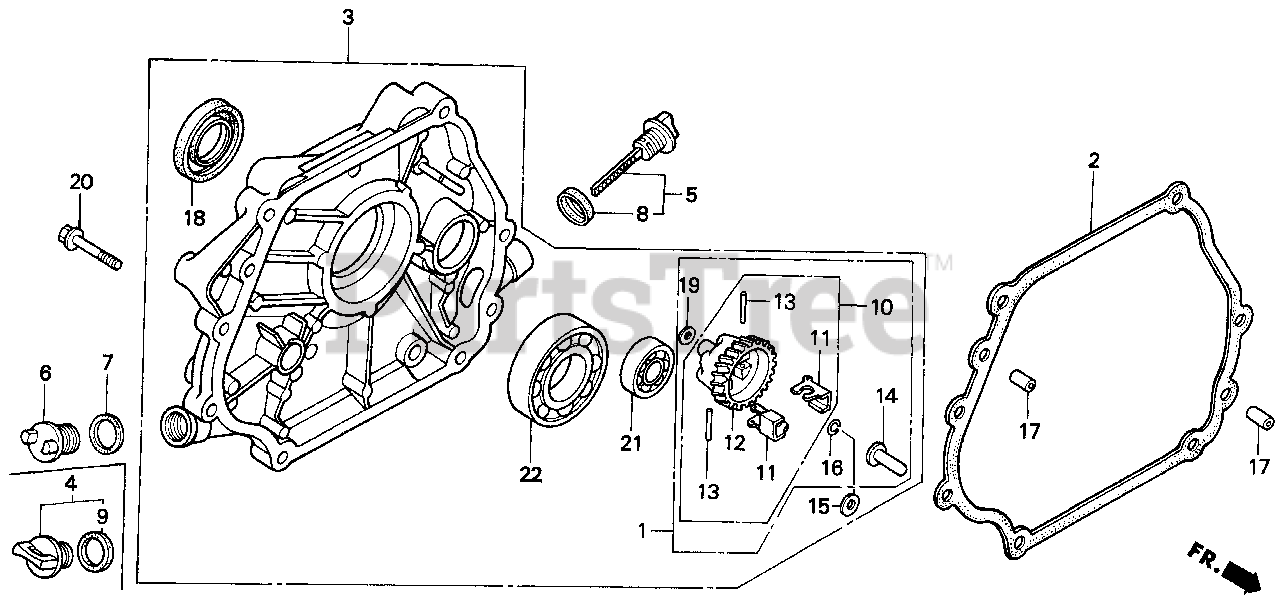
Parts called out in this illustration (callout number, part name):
1	GOVERNOR KIT (BALANCER)
2	GASKET, CASE COVER
3	COVER ASSY., CRANKCASE (Q-TYPE)(BALANCER)
5	CAP ASSY., OIL FILLER
6	CAP, OIL FILLER
7	GASKET, OIL FILLER CAP
8	GASKET, OIL FILLER CAP
10	GOVERNOR ASSY. (BALANCER)
11	WEIGHT, GOVERNOR
12	HOLDER, GOVERNOR WEIGHT
13	PIN, GOVERNOR WEIGHT
14	SLIDER, GOVERNOR
15	WASHER (6X16)
16	CLIP, GOVERNOR HOLDER
17	PIN, DOWEL (8X12)
18	OIL SEAL (30X46X8)
19	WASHER, PLAIN (6MM)
20	BOLT, FLANGE (8X35)
21	BEARING, RADIAL BALL (6202)
22	BEARING, RADIAL BALL (6206)
